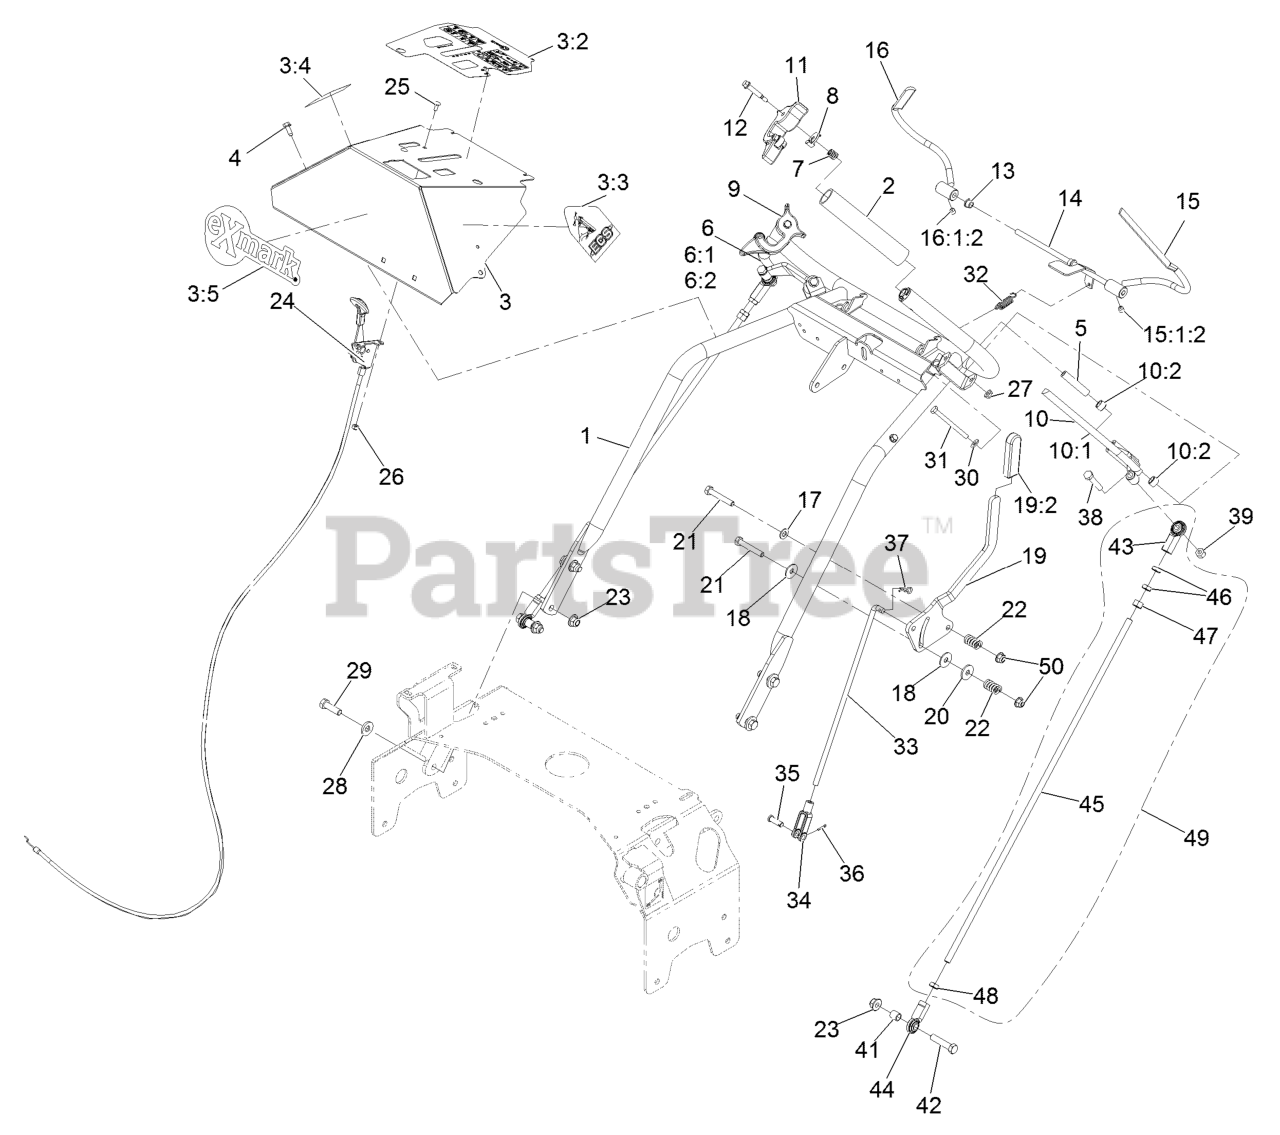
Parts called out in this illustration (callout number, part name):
1	WELD, HANDLE
2	GRIP-BAR, HANDLE
3	ASM, CONSOLE W/ DECALS
3:2	DECAL-CONSOLE TTX EFI
3:3	DECAL,LH ECS INSTRUCTION
3:4	DECAL,RH ECS INSTRUCTION
3:5	DECAL,EXMARK LOGO
4	SCREW-HWH
5	BUSHING-LEVER, DRIVE
6	DRIVE LEVER-ASM, RH
6:1	WLD,RH DRIVE LEVER
6:2	BUSHING-SLEEVE
7	SPRING-TANK, FUEL
8	LATCH, ECS
9	ASM,LATCH RH THUMB
10	DRIVE LEVER-ASM, LH
10:1	WLD,LH DRIVE LEVER
10:2	BUSHING-SLEEVE
11	ASM,LATCH LH THUMB
12	SCREW-SHOULDER
13	BUSHING-NYLON
14	WLD,OPC LEVER AXLE
15	WLD,LH OPC LEVER
15:1:2	SCREW-SET
16	WLD,RH OPC LEVER
16:1:2	SCREW-SET
17	WASHER-PLAIN
18	WASHER-FRICTION
19	LEVER, SHIFT W/GRIP
19:2	GRIP-HANDLE, STEERING
20	WASHER-FRICTION
21	SCREW-HH
22	SPRING-COMPRESSION
23	NUT-HF, NI
24	CONTROL-THROTTLE
25	BOLT-CARR
26	NUT-LOCK, NI
28	WASHER-BELLEVILLE
29	SCREW-HH
30	WASHER-FLAT
31	SCREW-HH
32	SPRING-EXTENSION
33	ROD,SPEED CONTROL
34	YOKE-ADJUSTABLE
35	PIN-CLEVIS
36	PIN-COTTER
37	PIN-COTTER
38	SCREW-HH
39	NUT-LOCK, NI
41	SPACER-TUBE, PUMP LINK
42	SCREW-HH
43	JOINT-BALL, END
44	JOINT-BALL END, LH
45	LINK,DRIVE (PLTD)
46	NUT-HJ
47	NUT-HEX
48	NUT-HEX JAM, LH
49	DRIVE LINK ASM
50	NUT-HF, NI
